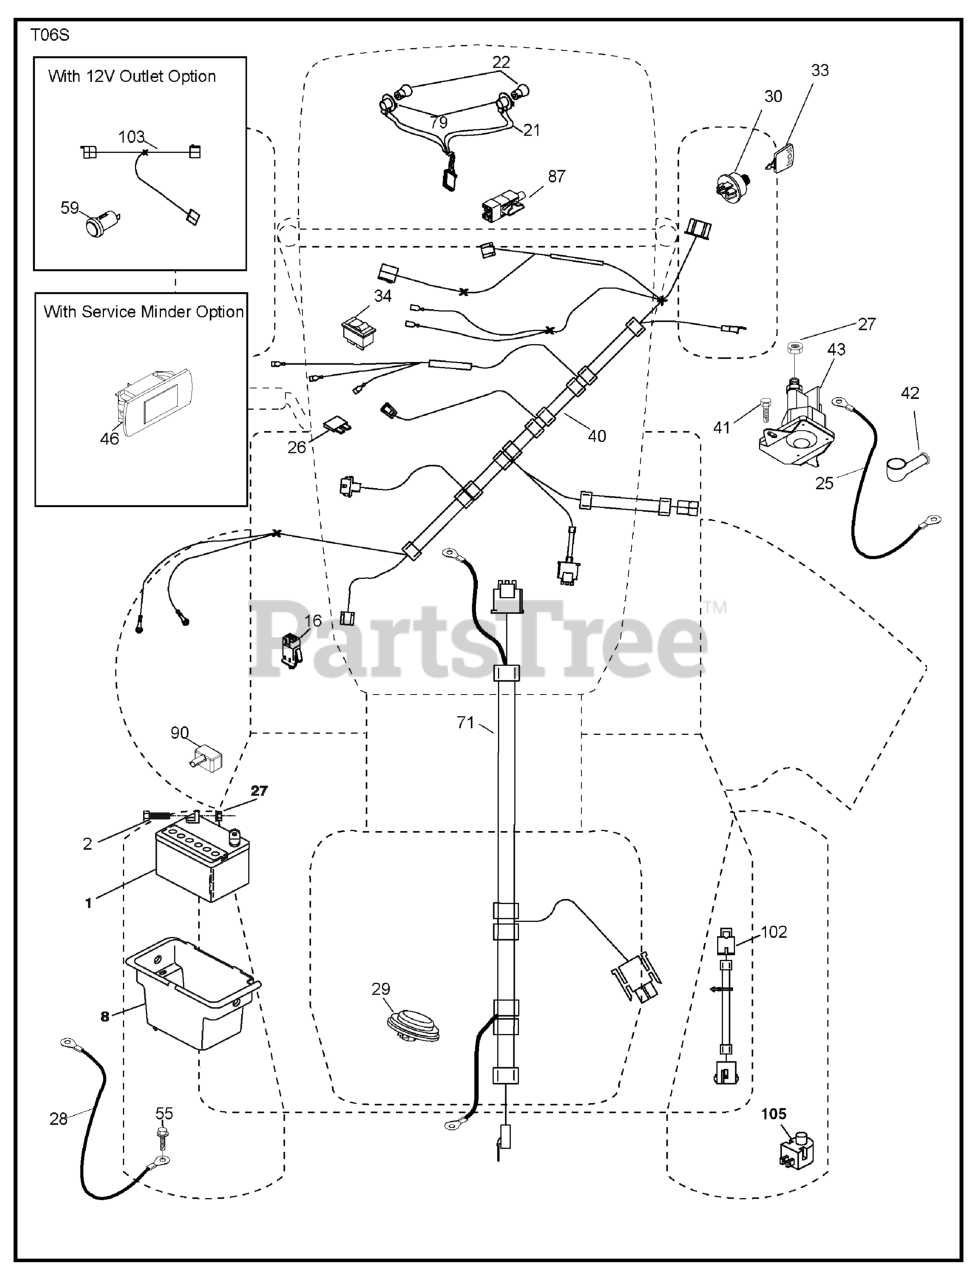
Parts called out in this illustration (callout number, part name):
1	Battery
2	Bolt Hex Hd 1/4-20 unc x 3/4
8	Box Battery
16	Switch Interlock
21	Harness Socket Light
22	Bulb, Light #1156
24	Cable Battery
25	Cable Starter 6 Ga. BL/Red 14.5
27	Nut Keps Hex 1/4-20 unc
28	Cable Ground
29	Switch Seat
30	Switch Ign
33	Key/Chain
34	Switch Light/Reset
40	Harness Dash
41	Screw 1/4-20 unc x 1/2
42	Cover Terminal Red
43	Solenoid
55	Screw 5/16-18 x 3/4
71	Harness Ign. Chass.
79	Socket Asm. Bulb
87	Switch Clutch Cable
90	Cover Terminal
102	Harness Pigtail
105	Switch Reverse
